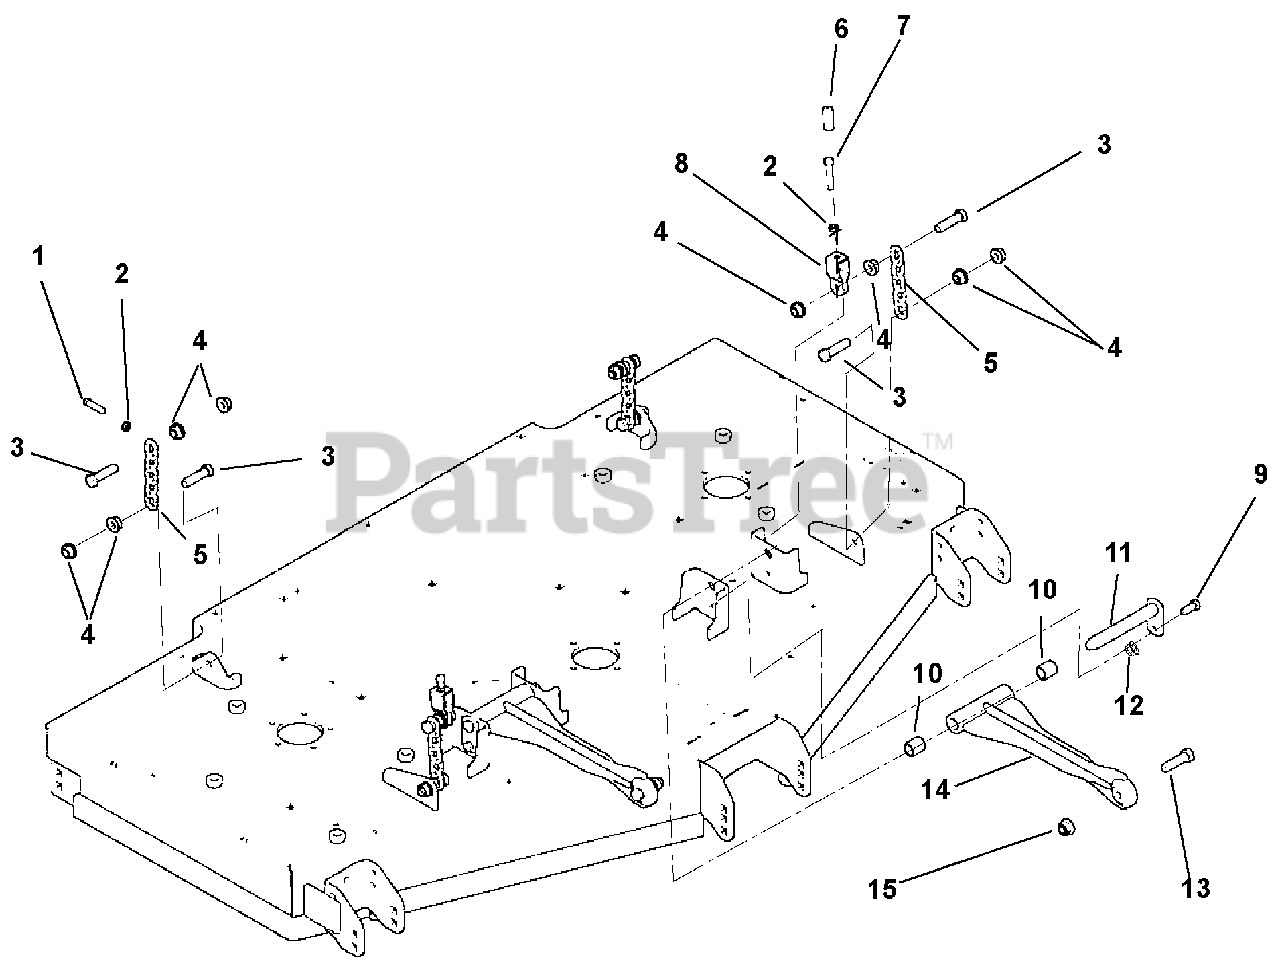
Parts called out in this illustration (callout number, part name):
1	Bolt, Hex .312-18 X 1.50
2	Jam Nut, .312-18
3	Bolt, Hex M12-1.75 x 50
4	Nut, Spin Lock Flange M12-1.75
5	Chain, Link
6	Cap, Vinyl .50 ID x 1.50 LG x .055
7	Bolt, Hex .312-18 x 2.00
8	Bracket, Deck Leveling
9	Bolt, Hex .38-16 x 1.00
10	Bearing, .75 x .875 x 1.00
11	Pin, Weldment Mower Mounting
12	Nut, Lylock Flanged .375-16
13	Bolt, Hex .50-13 x 2.00
14	Weldment Deck Stablizing Arm
15	Nut, Nylock Flanged .50-13
